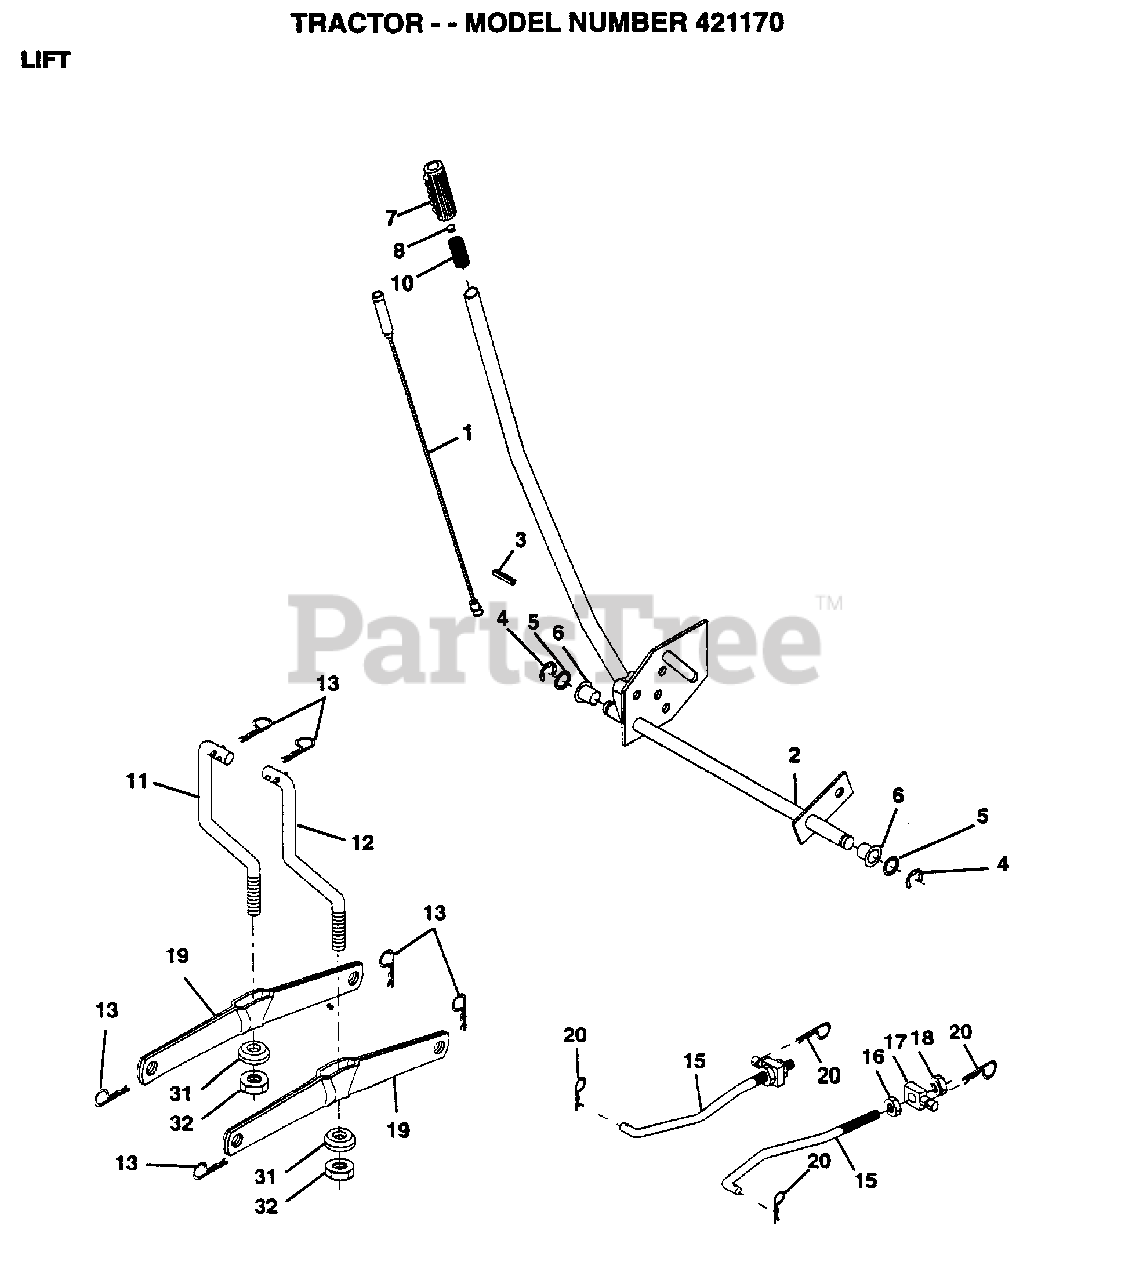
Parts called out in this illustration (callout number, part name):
1	WIRE ASM
2	HANDLE.LIFT.LH.
3	PIN GROOVE
5	WASHER
6	NYLON BEARING
7	GRIP
15	LINK.FRONT
16	NUT
17	TRUNION
18	NUT.LK.W/WSH.1/2.
19	ARM SUSP REAR
20	RETAINER.SPRING
31	BEARING PVT LH
32	NUT.CROWNLOCK.3/8
